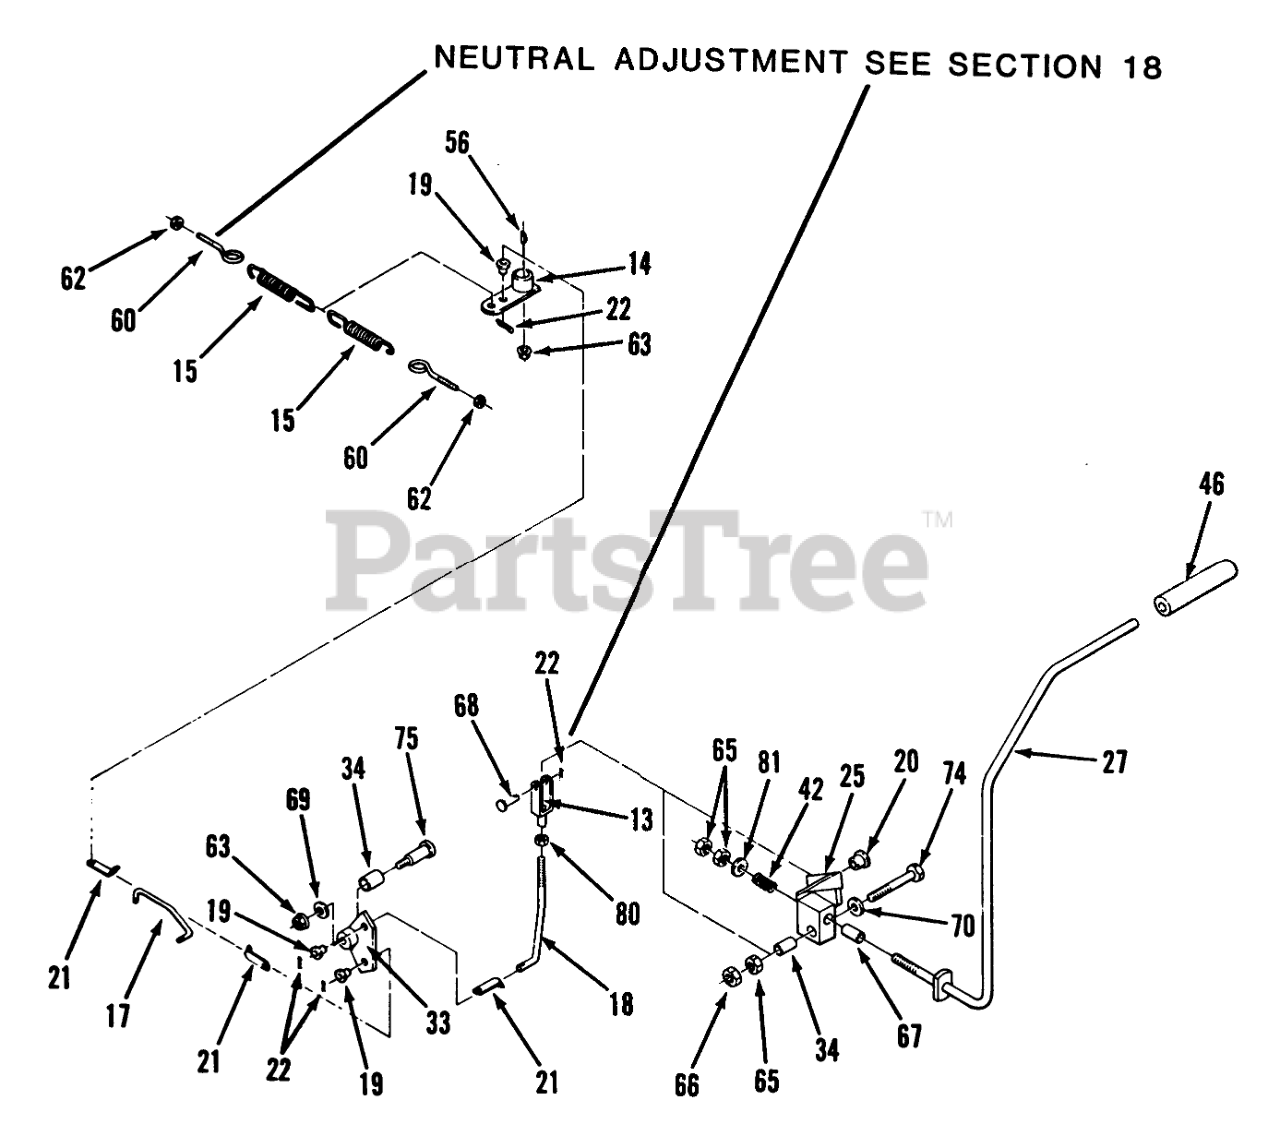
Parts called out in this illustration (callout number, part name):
13	Threaded Yoke
14	Hydro Control Arm
15	Spring
17	Lower Drive Linkage RH
18	LINKAGE-UPPER DRIVE
19	Nylon Bushing .296
20	Nylon Bushing 5/16
21	BACKING CLIP
22	HAIRPIN
25	STEERING LEVER LH
27	Steering Lever LH
33	PIVOT BLOCK
34	BUSHING
42	Spring
46	GRIP-HANDLE
56	KEY WOODR 1/8X1/2 DI
60	Eye Bolt
62	Nut
63	NUT
65	Eslok Nut
66	Jam Nut
67	Bronze Bushing
68	PIN CLEVIS 5/16X1
69	Washer
70	WASHER 7/16 SAE
74	HEX HD CAP SCREW
75	Shoulder Bolt 1/2-13 x 1 3/4
80	Nut-Lock
81	Washer
